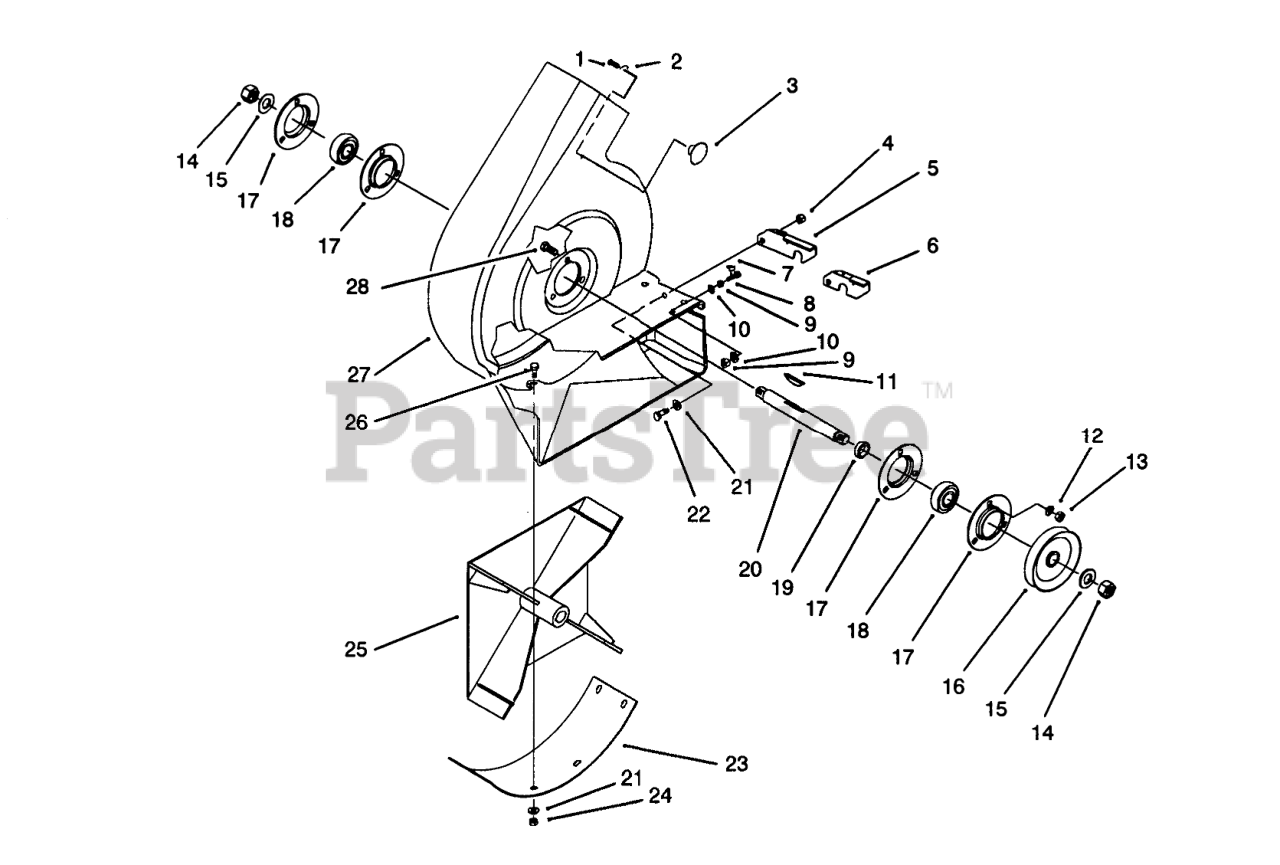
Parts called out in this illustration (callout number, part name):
1	SCREW-PPHTF
2	WASHER-PLAIN
4	NUT-LOCK, NI
5	48" BLOWER LATCH B
6	42" BLOWER LATCH B
7	SPRING-EXTENSION
8	SCREW-HWH
9	NUT-HEX
10	WASHER-FLAT
12	WASHER-LOCK
13	NUT-HEX
14	NUT-JAM
15	WASHER-LOCK
16	PULLEY-BLOWER
17	FLANGE
18	BEARING-BALL
19	Spacer
20	SHAFT-BLOWER
21	WASHER-FLAT
22	SCREW-HH
23	COVER-BLOWER, BOTTOM
24	NUT-LOCK, NI
25	Impeller
26	SCREW-CARRIAGE
27	HOUSING-VAC, BLOWER
28	SCREW-CARR
